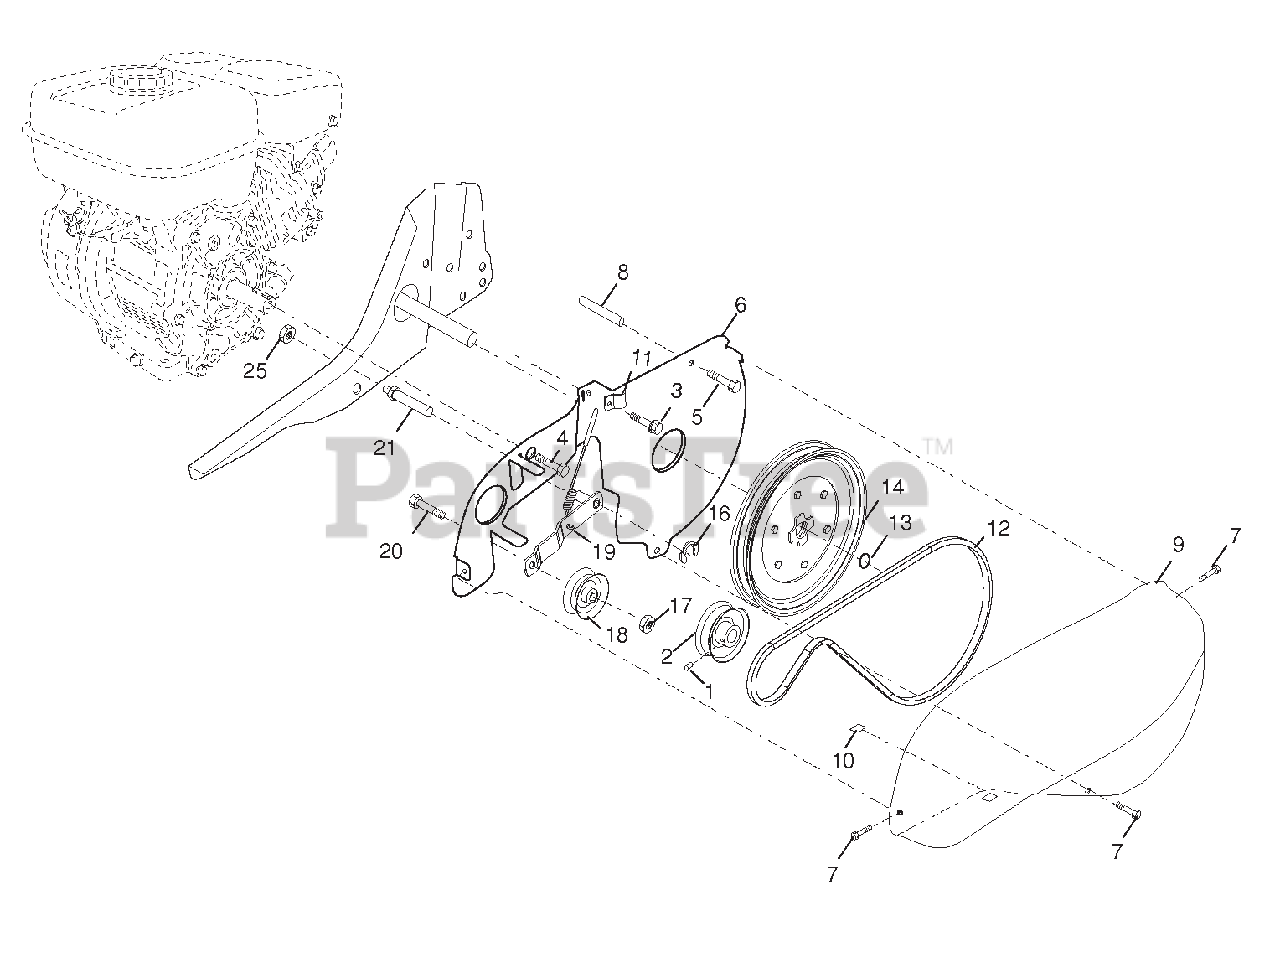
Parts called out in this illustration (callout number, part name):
1	Screw Set 5/16-18 x 3/8 Patch
2	Sheave, Engine
3	Screw, Tap Hex Head
4	Bolt, Hex Head 5/16-24 unf x 1
5	Bolt, Thd Roller 1/4-20 x 2-1/
6	Shield, Inner Belt Guard
7	Screw Hex Wsh Hd #8-18 x 1/2
8	Spacer Split
9	Guard, Belt
10	Pad, Idler
11	Clip, Cable
13	Ring, Retainer
14	Sheave, Transmisison
16	Ring, Klip
17	Nut, Hex, Jam 3/8-16
18	Pulley, Idler
19	Arm, Idler
20	Bolt, Hex Head 3/8-16 x 1-1/4
21	Shaft, Idler Arm
25	Nut, Hex, Jam 5/16-18
